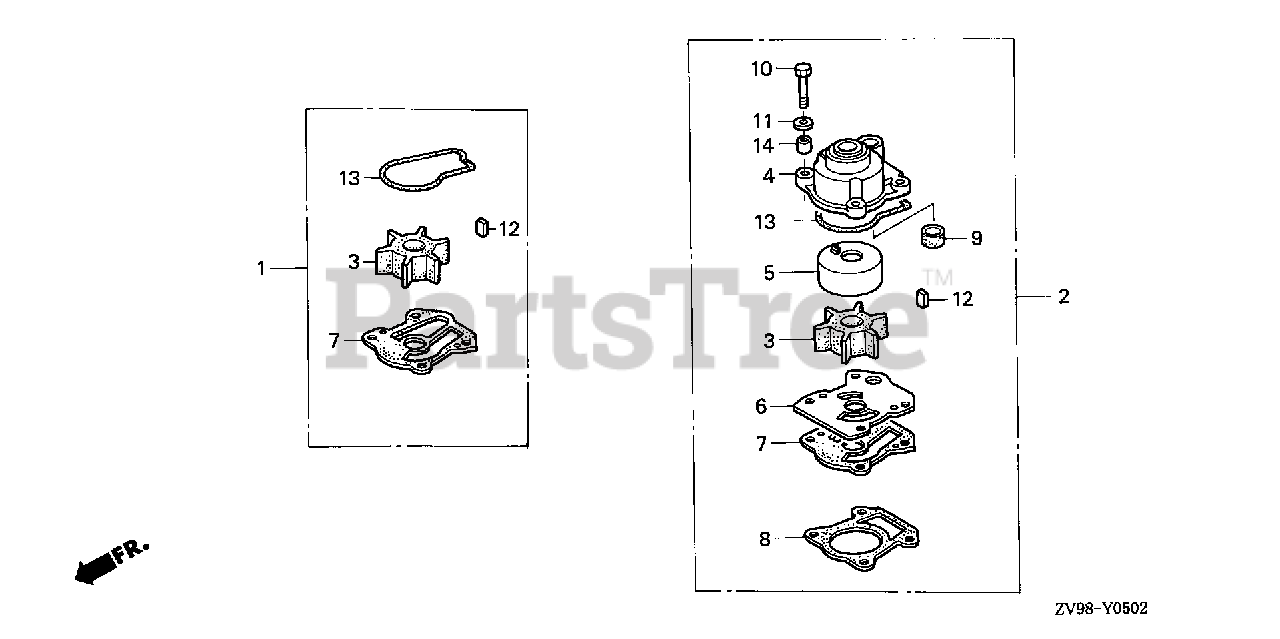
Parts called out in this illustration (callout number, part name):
1	PUMP KIT, IMPELLER
2	PUMP KIT, IMPELLER
3	IMPELLER, PUMP
4	HOUSING, IMPELLER
5	LINER, PUMP
6	COVER, IMPELLER
7	GASKET B, IMPELLER
8	GASKET, WATER PUMP
9	RING, WATER TUBE SEAL
10	BOLT, HEX. (6X40)
11	WASHER (6MM)
12	KEY, WOODRUFF (5MM)
13	O-RING, WATER PUMP
14	COLLAR, IMPELLER HOUSING
